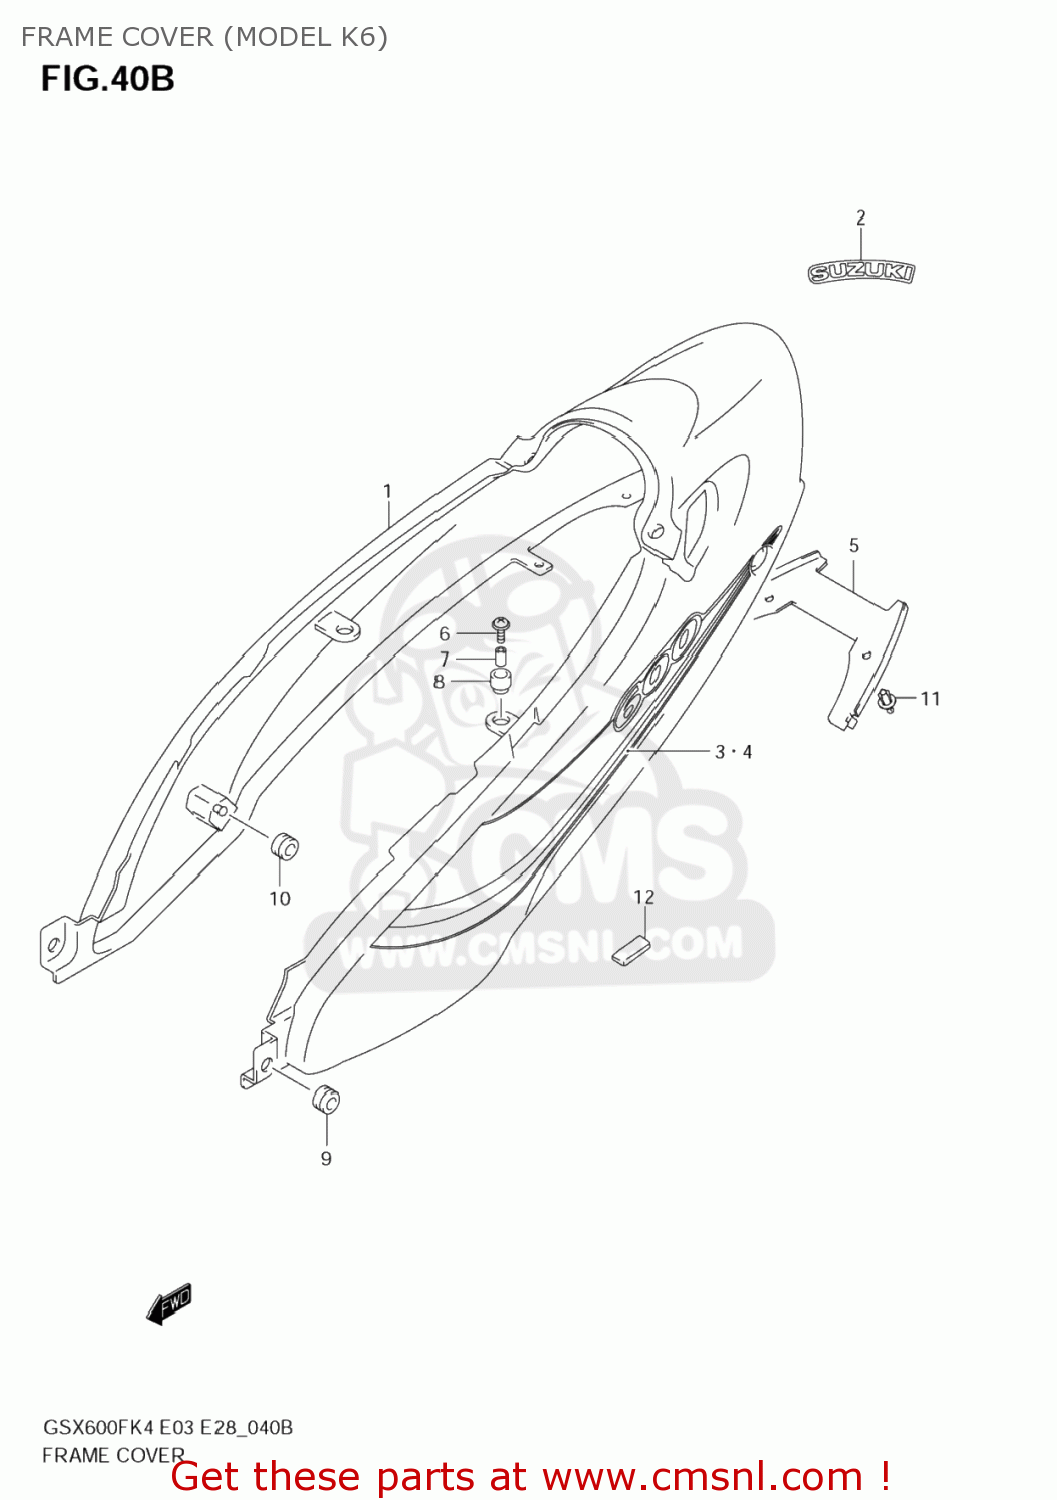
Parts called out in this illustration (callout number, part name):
1	COVER COMP,FRA
2	EMBLEM,SUZUKI
3	TAPE,FRAME COVER STRIPE,R
4	TAPE,FRAME COVER STRIPE,L
5	COVER,FRAME LWR
6	SCREW(6X20)
7	SPACER(6.5X10X9.4)
8	CUSHION
9	CUSHION
10	CUSHION
11	CLIP(BLACK)
12	CUSHION
